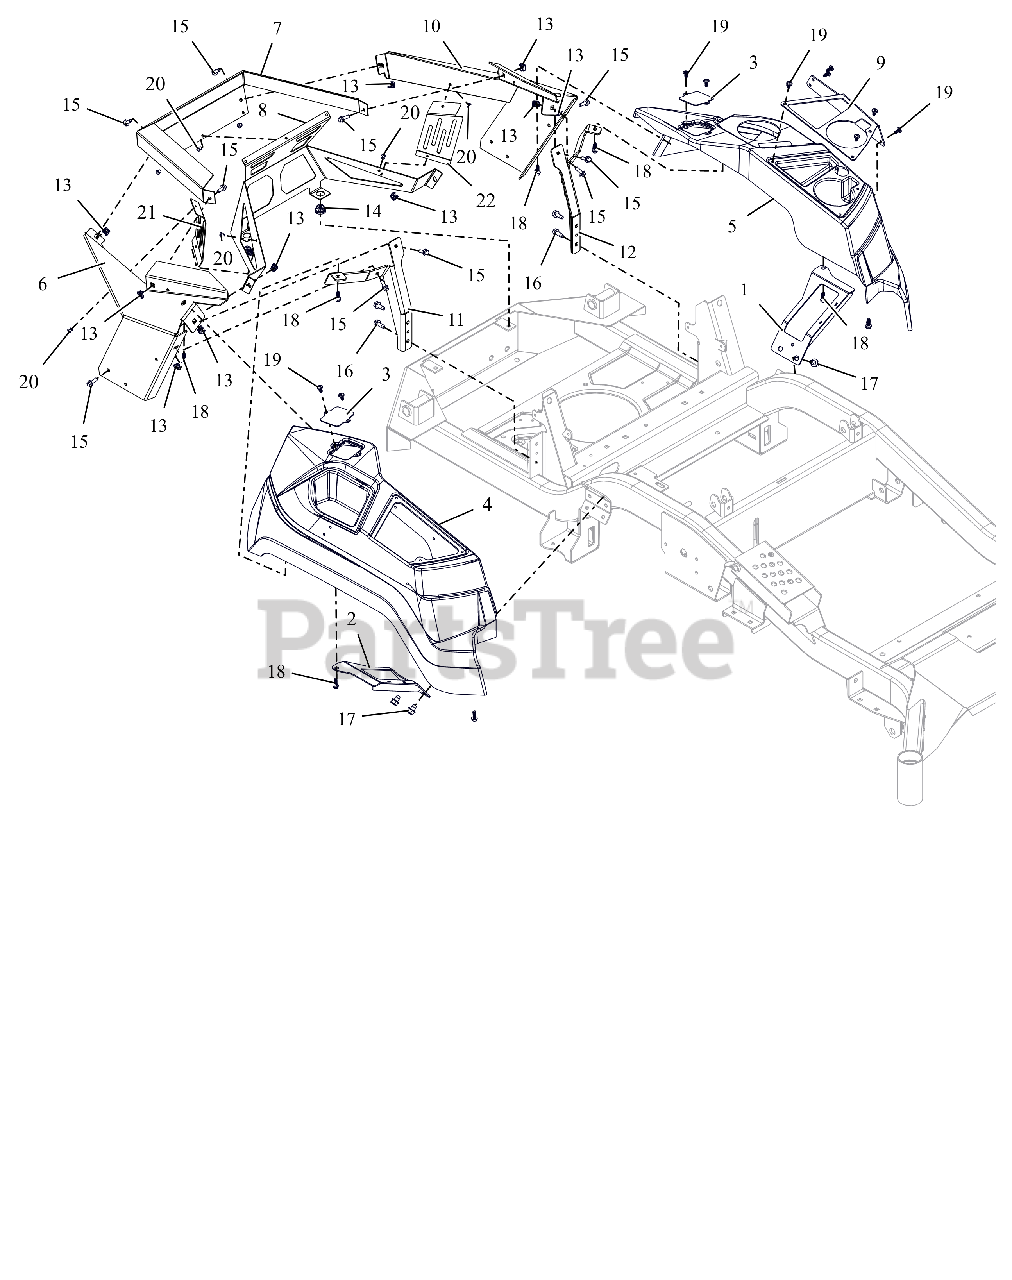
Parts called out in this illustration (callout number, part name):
1	WLDMT, LH FENDER MOUNT
2	WLDMT, RH FENDER MOUNT
3	PLATE, ROPS HOLE-HD
4	FENDER, RH APEX - 2017
5	FENDER, LH APEX
6	PANEL,RIGHT REAR FENDER MOUNT
7	GUARD,ENGINE WRAP
8	GUARD,ENGINE
9	PLATE, APEX CUP HOLDER COVER
10	PANEL,LEFT REAR FENDER MOUNT
11	BRKT, RH FENDER MTG. APEX
12	BRKT, LH FENDER MTG -APEX
13	NUT RETNR .25-20
14	GROMMET, 10MM BOLLHOFF
15	BLT,HEX-FLG .25-20X.75 G5 BFP
16	SCR,TAP .312-18X.75 HWH TR ZCC
17	SCR,TAP .375-16X.50 HWH TR ZCC
18	SCR, PLASTITE .25-10X.75 ZCC
19	SCR-PAN .25-15X.50 6L H/LZB500
20	RIVET, .1875 AL/AL .126-.250
21	SHIELD,RH ENGINE GUARD VALVE
22	SHIELD,LH ENGINE GUARD VALVE
